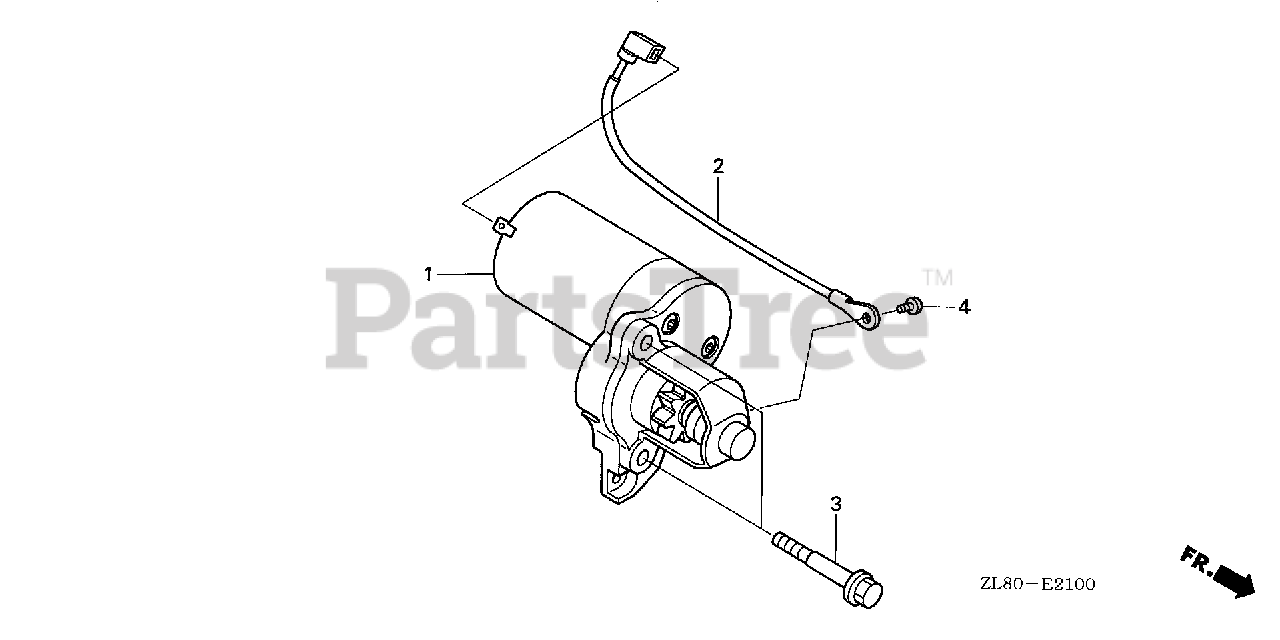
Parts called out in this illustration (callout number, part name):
1	STARTER MOTOR ASSY.
2	WIRE, TERMINAL GROUND
3	BOLT, SPECIAL (6MM)
4	SCREW, PAN (5X8)
